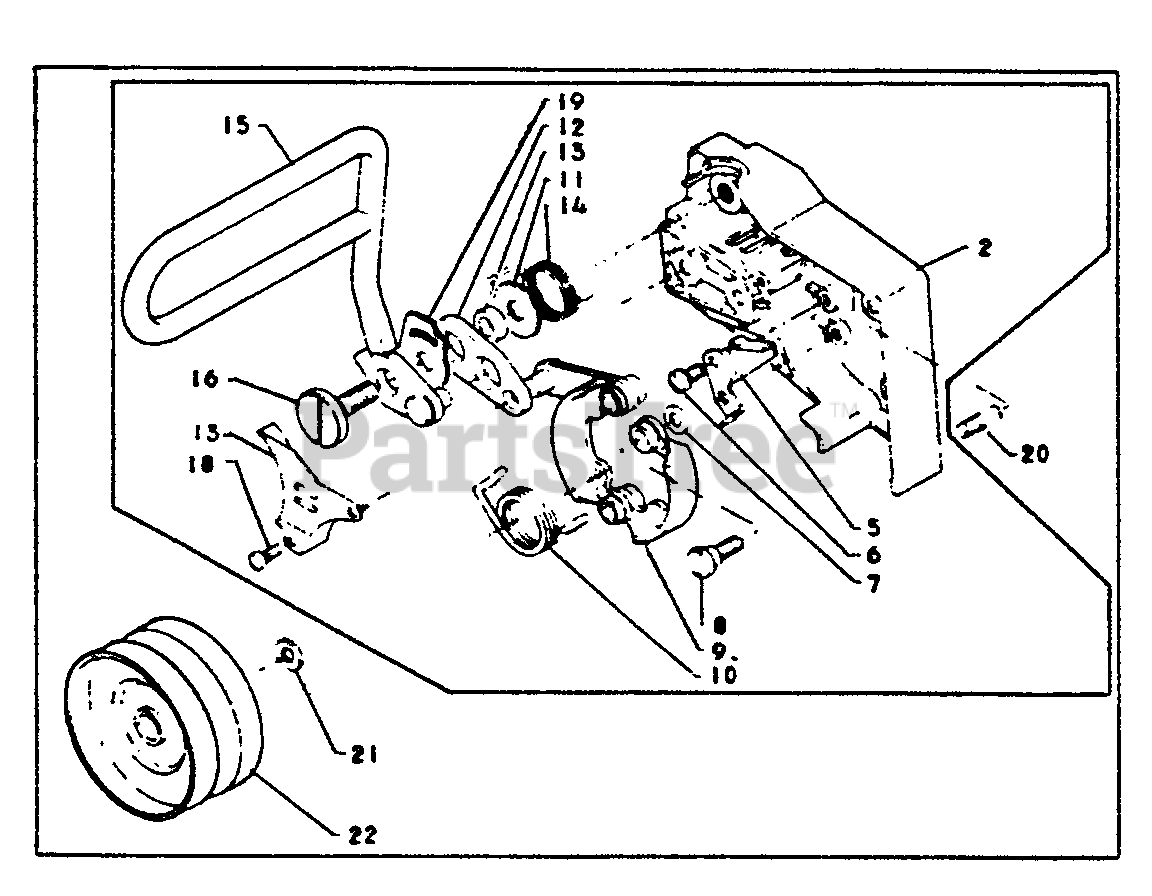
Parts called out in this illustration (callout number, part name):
2	COVER, GUIDE BAR
5	GUIDE, BRAKE SHOE
6	SCREW - 5X8
7	WASHER - 6
9	SHOE, BRAKE
10	SPRING
11	SPACER
12	CONNECTOR
13	SPACER
14	SPRING, RETURN
15	HANDLE, BRAKE
17	SEAL
18	SCREW - 4X10
19	WASHER
20	PIN - LOCATING
21	WASHER
22	DRUM, CLUTCH
22	CHAIN BRAKE ASSY
